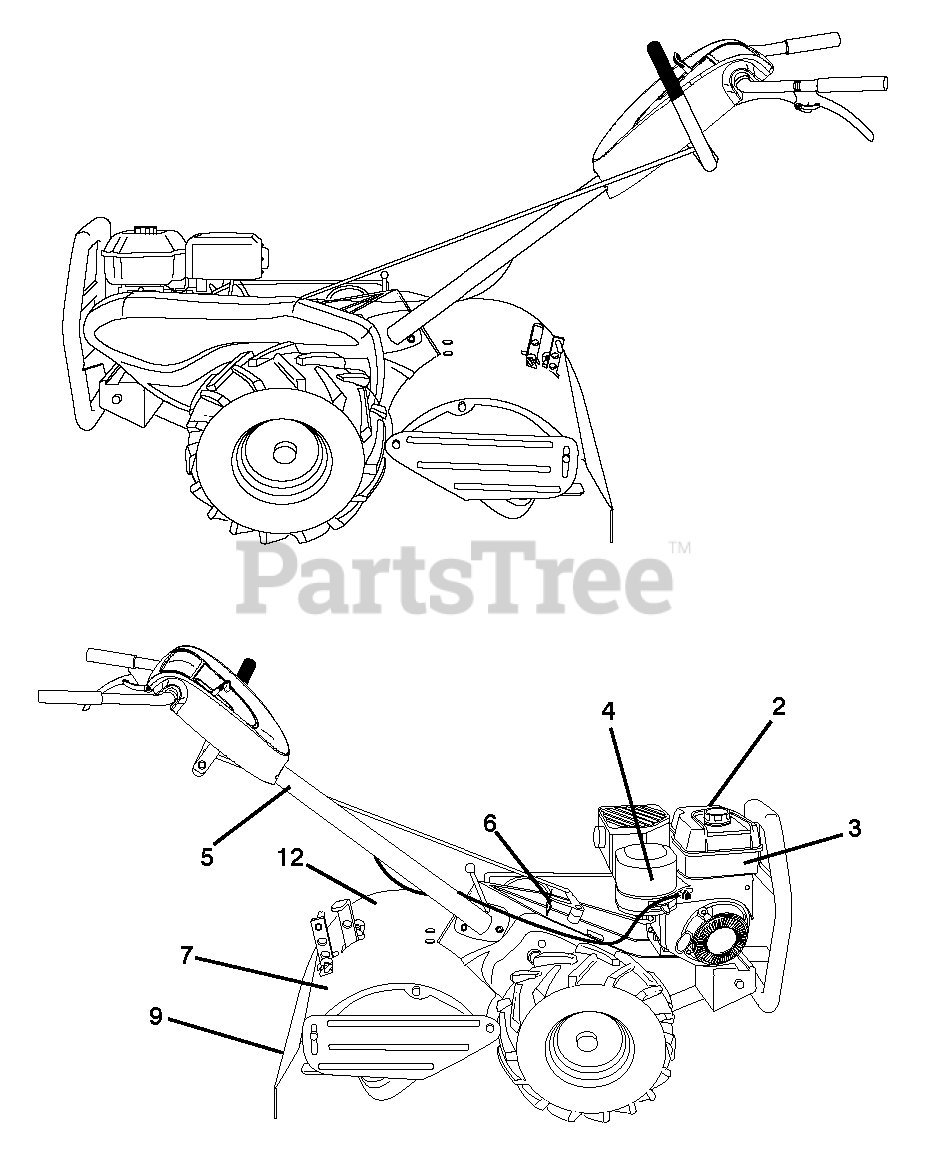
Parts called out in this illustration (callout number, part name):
2	DECAL,ETHANOL E85 WARNING
3	DECAL, WARNING SPARK ARRESTOR
4	DECAL.B&S.950S
5	DECAL TI (2 2)
6	DECAL.SHIFT.INDICATOR.DRT
7	DECAL.REVERSE.HUSQ.TILLER
9	DECAL.DRT.WARN.ENG/F
12	DECAL.FOWARD.HUSQ.TILLER
